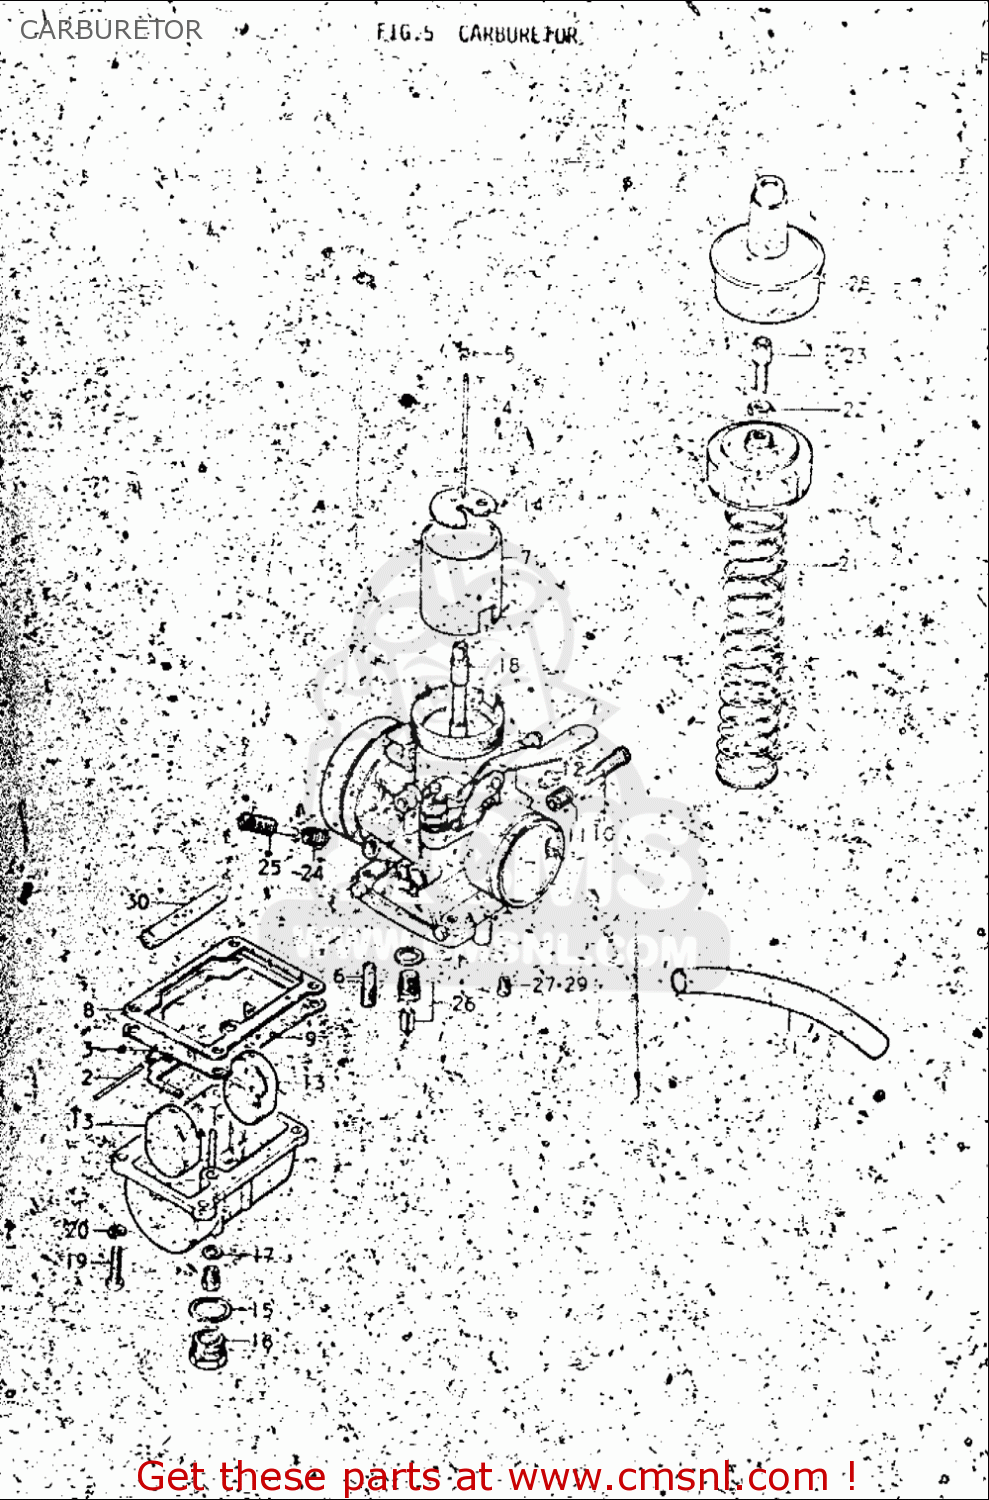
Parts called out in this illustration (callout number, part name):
1	GASKET,MAIN JET HOLDER (NAS)
5	CLIP
6	JET,PILOT(40)
8	GASKET,FLOAT CAHMBER (NAS)
11	SPRING,THROTTLE SCREW
12	NUT, STOP SCREW
13	FLOAT
15	GASKET,DRAIN PLUG
17	WASHER
19	SCREW
20	WASHER,LOCK
22	NUT
23	ADJUSTER,CABLE
24	SPRING
25	SCREW,PILOT AIR
26	VALVE ASSY,NEEDLE
27	JET,MAIN(230)
28	CAP
29	JET,MAIN(180)
30	HOSE(3.5X6.5X600)
31	HOSE(3.5X6.5X600)
